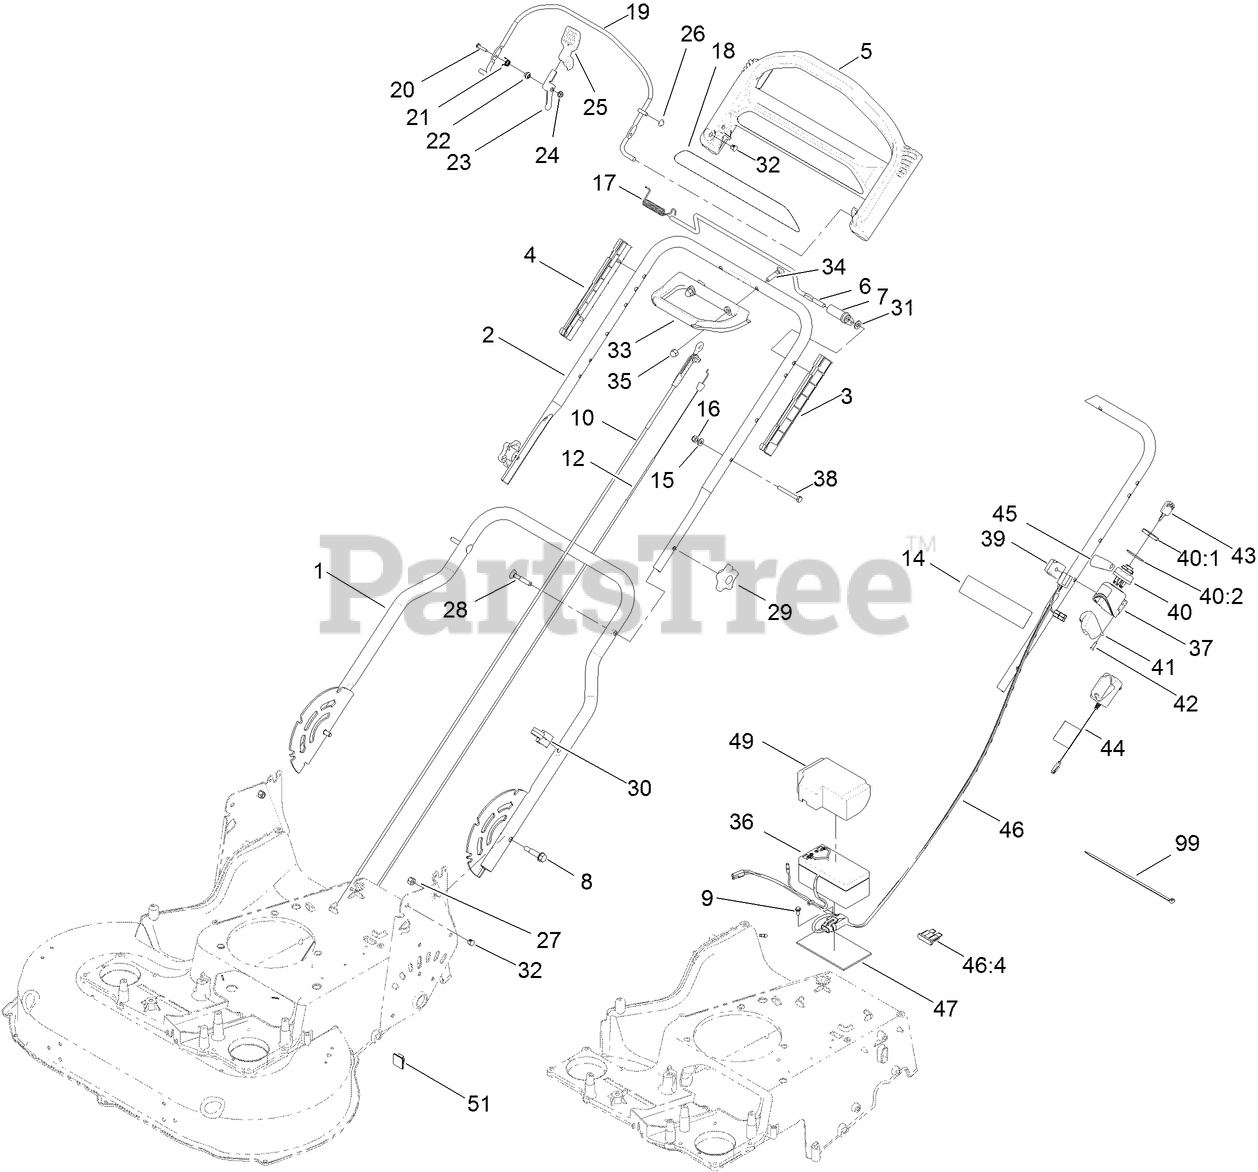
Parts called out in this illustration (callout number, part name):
1	HANDLE-LOWER
2	HANDLE-UPPER
3	GUIDE-LH
4	GUIDE-RH
5	HANDLE-CONTROL
6	BAR-CONTROL, TRACTION
7	LEVER-TRACTION
8	BOLT-SHOULDER, HHF
9	SCREW-TAPTITE
10	CABLE-BRAKE, BBC
12	CABLE-TRACTION
14	DECAL-WARNING
15	WASHER-FLAT
16	NUT-LOCK, NI
17	Spring-Torsion
19	BAIL-BRAKE
20	SCREW-HWH
21	SPRING-TORSION
22	SPACER
23	LEVER
24	NUT-LOCK, FLANGE
26	NUT-SPEED
27	NUT-LOCK, NI
28	SCREW-HANDLE
29	KNOB-HANDLE
30	GUIDE-CABLE
31	WASHER-PLAIN
32	Plug-Dome
33	HANDLE-ASSIST, TRACTION
34	BOLT-CARRIAGE
35	NUT-LOCK, CAP
36	BATTERY-WET
37	HOUSING-SWITCH, KEY
38	SCREW-HH
39	ANCHOR-CABLE, UPPER
40	SWITCH-STARTER
40:1	NUT-HH
40:2	WASHER-TOOTH, INTERNAL
41	COVER-SWTCH
42	SCREW-PPH
44	CHARGER-BATTERY
45	DECAL-SWITCH, IGNITION
46	HARNESS-WIRE
46:4	FUSE-40 AMP
47	FOAM-BATTERY
49	COVER-BATTERY
51	GUIDE-CABLE
99	TIE-CABLE
